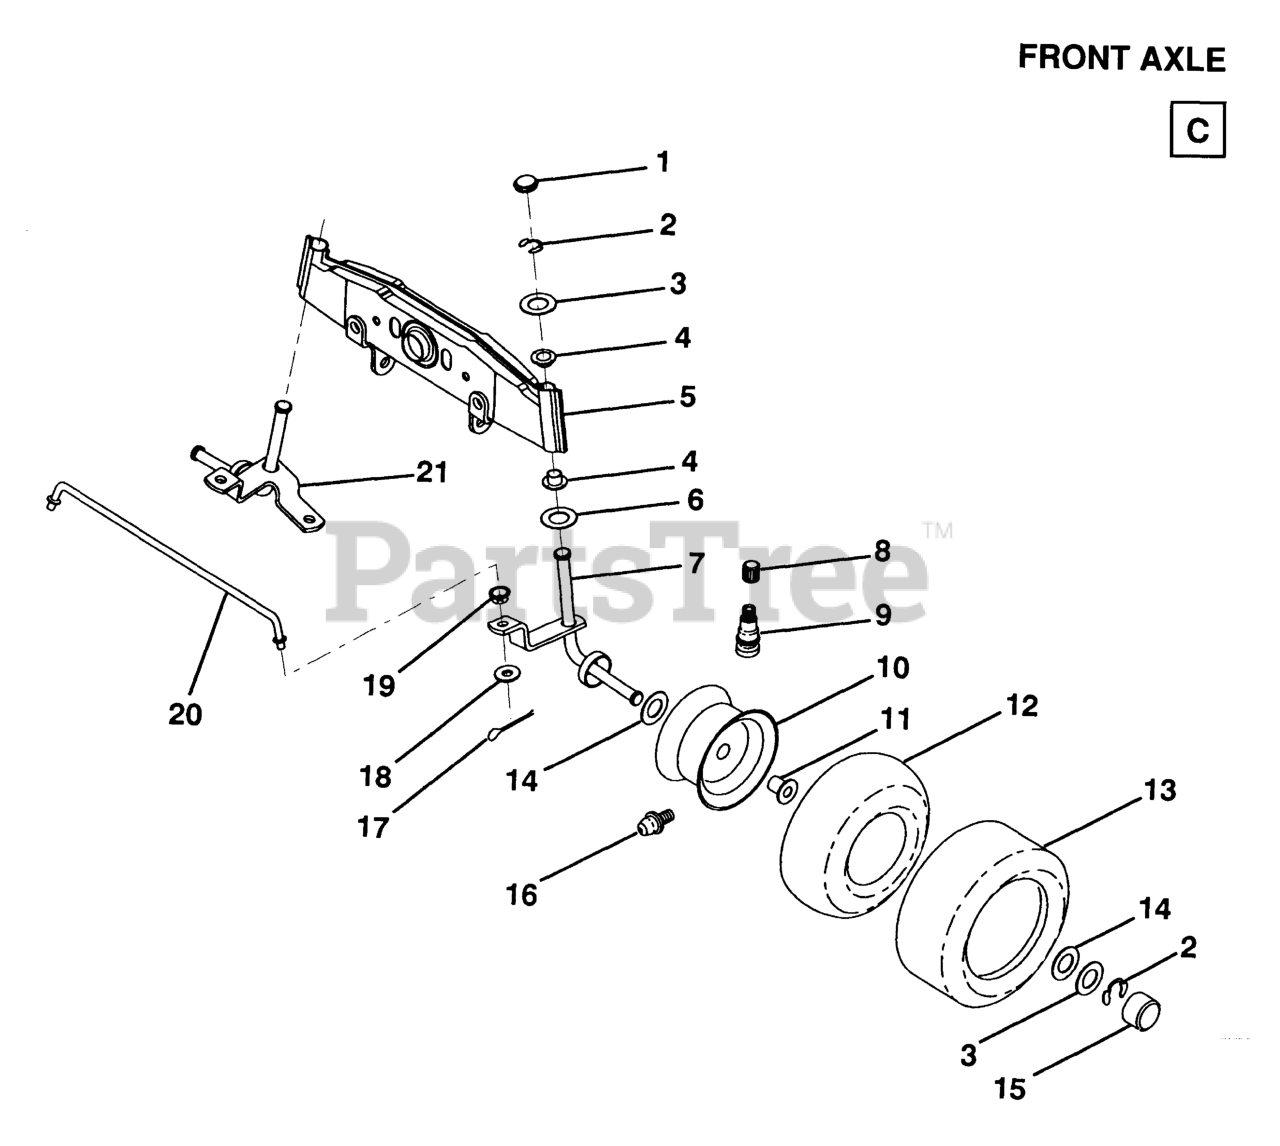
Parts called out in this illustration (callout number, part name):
1	CAP.SPINDLE.BLACK
6	THRUST WASHER
7	SPINDLE RH
9	VALVE STEM LT
10	RIM
11	BEARING.FLANGE
12	TUBE.5.3/4.5/6
13	TIRE.13X5-6.TURF.SAVER.FRONT
15	CAP.HUB.FRONT.LT.BLACK
16	FITTING LT.
17	PIN COTTER
18	WASHER
19	BUSHING.DRAGLINK (2 2)
21	SPINDLE LH
